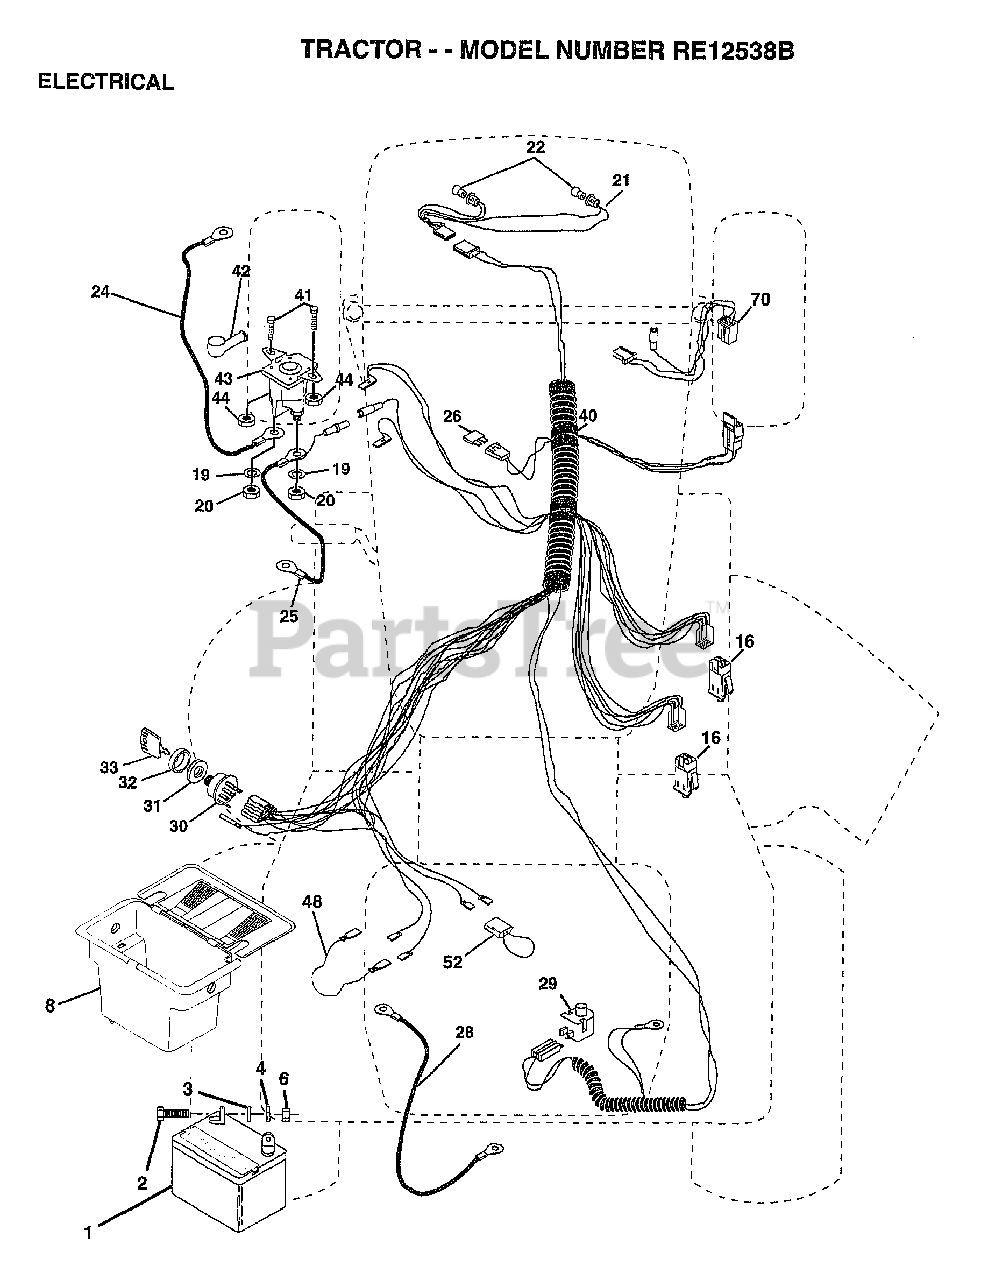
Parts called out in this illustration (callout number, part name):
3	WASHER
4	LOCKWASHER
8	"CASE,BATTERY.MECH"
9	HOSE CLAMP T
16	SWITCH INTERLOCK
20	NUT
21	"HARNESS,LIGHT SOC"
22	HEADLAMP BULB
24	"CABLE T, BATTERY"
25	CABLE.BTRY.6GA.RD
26	FUSE HYT
28	CABLE T
29	SWITCH SEAT
30	SWITCH IGN 4POS
31	NUT IGNITION
32	COVER KEY SWITCH
33	KEY
40	HARNESS-IGNITION
41	BOLT HXHD FIN
44	NUT HXKEP 1/4X20
48	ADAPTER AMMETER
52	PROTECTION LOOP
70	HARNESS ENG DUAL
